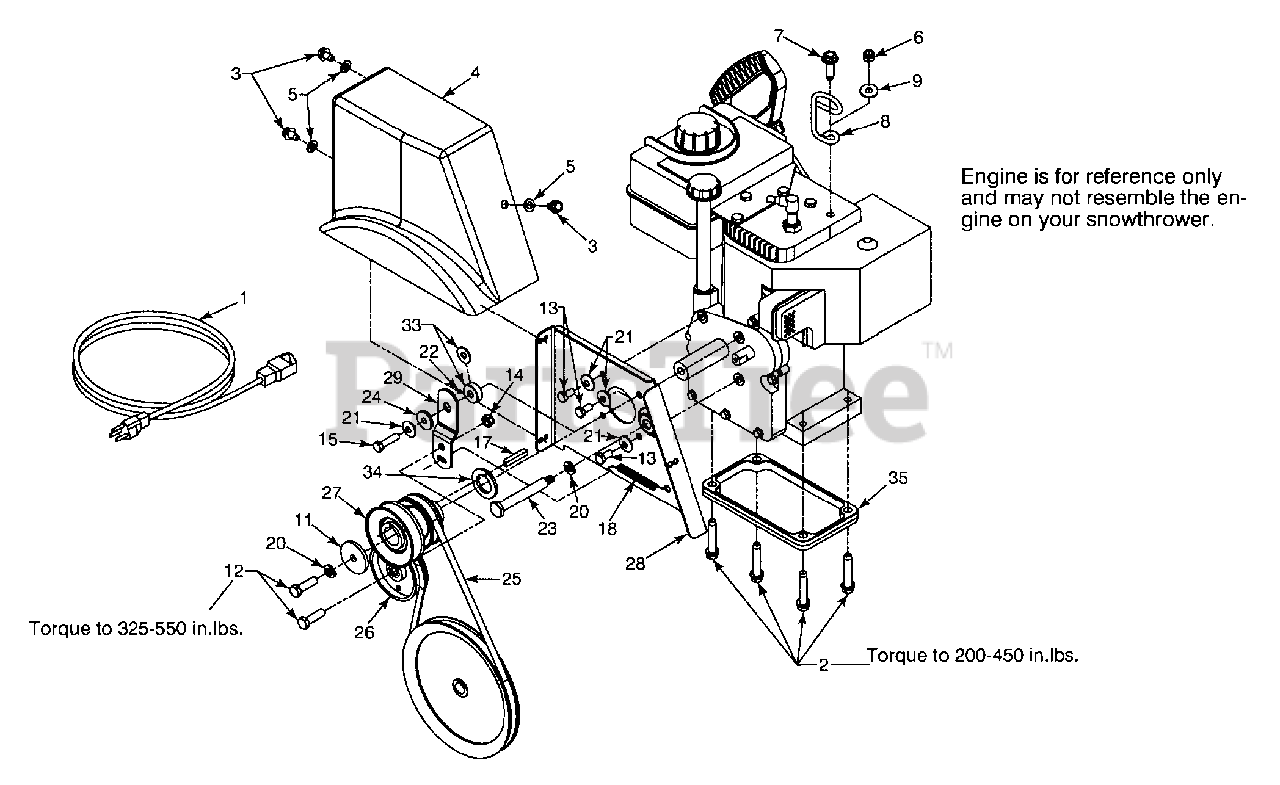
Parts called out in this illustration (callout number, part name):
1	Extension Cord 10 Ft.
2	Hex L-Wash TT Scr. 3/8-16 x 1.8
3	Hex Wash HD S-Tapp Scr 5/16-18 x .50
4	Plastic Belt Cover
5	Flat Washer .330 ID x .630 OD x .0635
6	Hex Ins. Locknut 1/4-20 Gr. 8 Nylon
7	Hex Wash Hd Tapp Scr 5/16-18 x 1.00
8	Cable Control Wire
9	Flat Washer .28 ID x .74 OD x .063
11	Flat Washer .39 ID x 1.75 OD x.1 75
12	Hex Screw 3/8-24 x 1.25 Gr. 8 Special
13	Hex Screw 5/16-24 x .625 Gr. 5
14	Hex Nut 3/8-24 Gr. 5 Nylon
15	Hex HD. Cap Scr. 5/16-24 x 1.25 Lg. Gr 5
17	Square Key 1/4 x 1/4 x 1.50" Lg.
18	Brake Return Ext. Spring 3.18" Lg.
20	Lockwasher Heavy 3/8" ID
21	Cupped Washer.340 ID x .872 OD x .06
22	Grease Arctic
23	Shoulder Screw.498 x 3.245 x 3/8-16
24	Shoulder Spacer .25 THK
25	V-Belt 3/8 x 35.5" Lg.
26	Flat Idler w/flanges 3.0 OD
27	Double Groove Engine Pulley
33	Spacer.33 ID x 1.01 OD x .36
34	Spacer 1.02 x 1.63 x .1425
35	Engine Spacer.560 Thick
